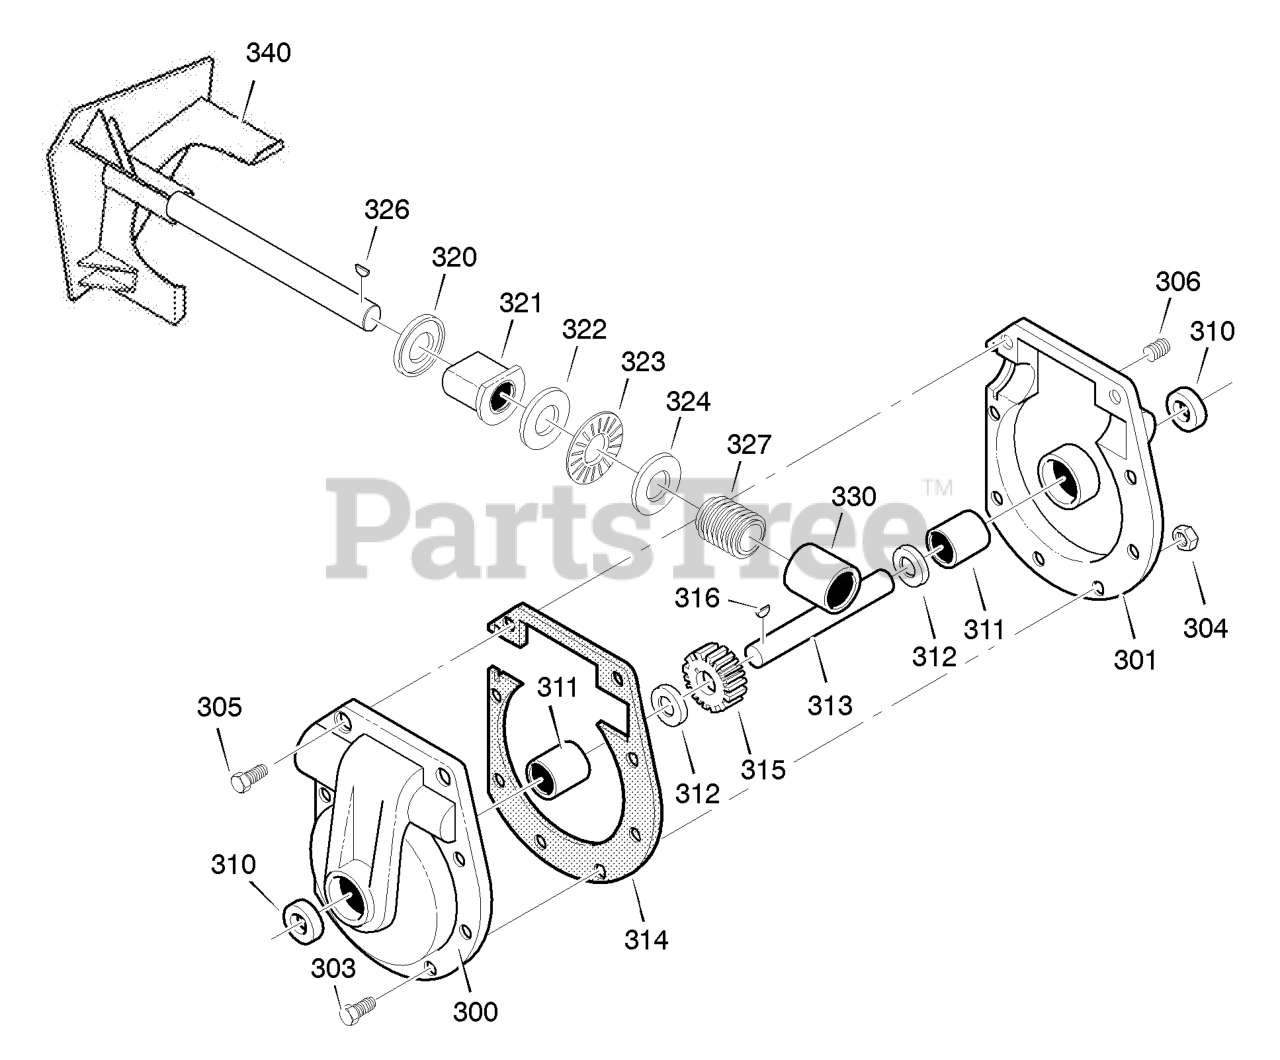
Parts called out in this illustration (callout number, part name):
300	CASE, GEAR, RH
301	CASE, GEAR, LH
303	SCREW, 5/16-24 x 1.00
304	NUT, 5/16-24
305	SCREW, 5/16-24 x 1.50
306	PLUG, PIPE
310	SEAL, OIL
311	BEARING
312	WASHER, FLAT
313	SHAFT, AUGER OUTPUT
314	GASKET, GEAR BOX
315	WORM GEAR
316	KEY, WOODRUFF #91
320	RING, QUAD
321	BEARING, FLANGE
322	WASHER, FLANGE
323	BEARING, ROLLER
324	WASHER, FLAT
327	GEAR, WORM
330	BEARING
340	IMPELLER
